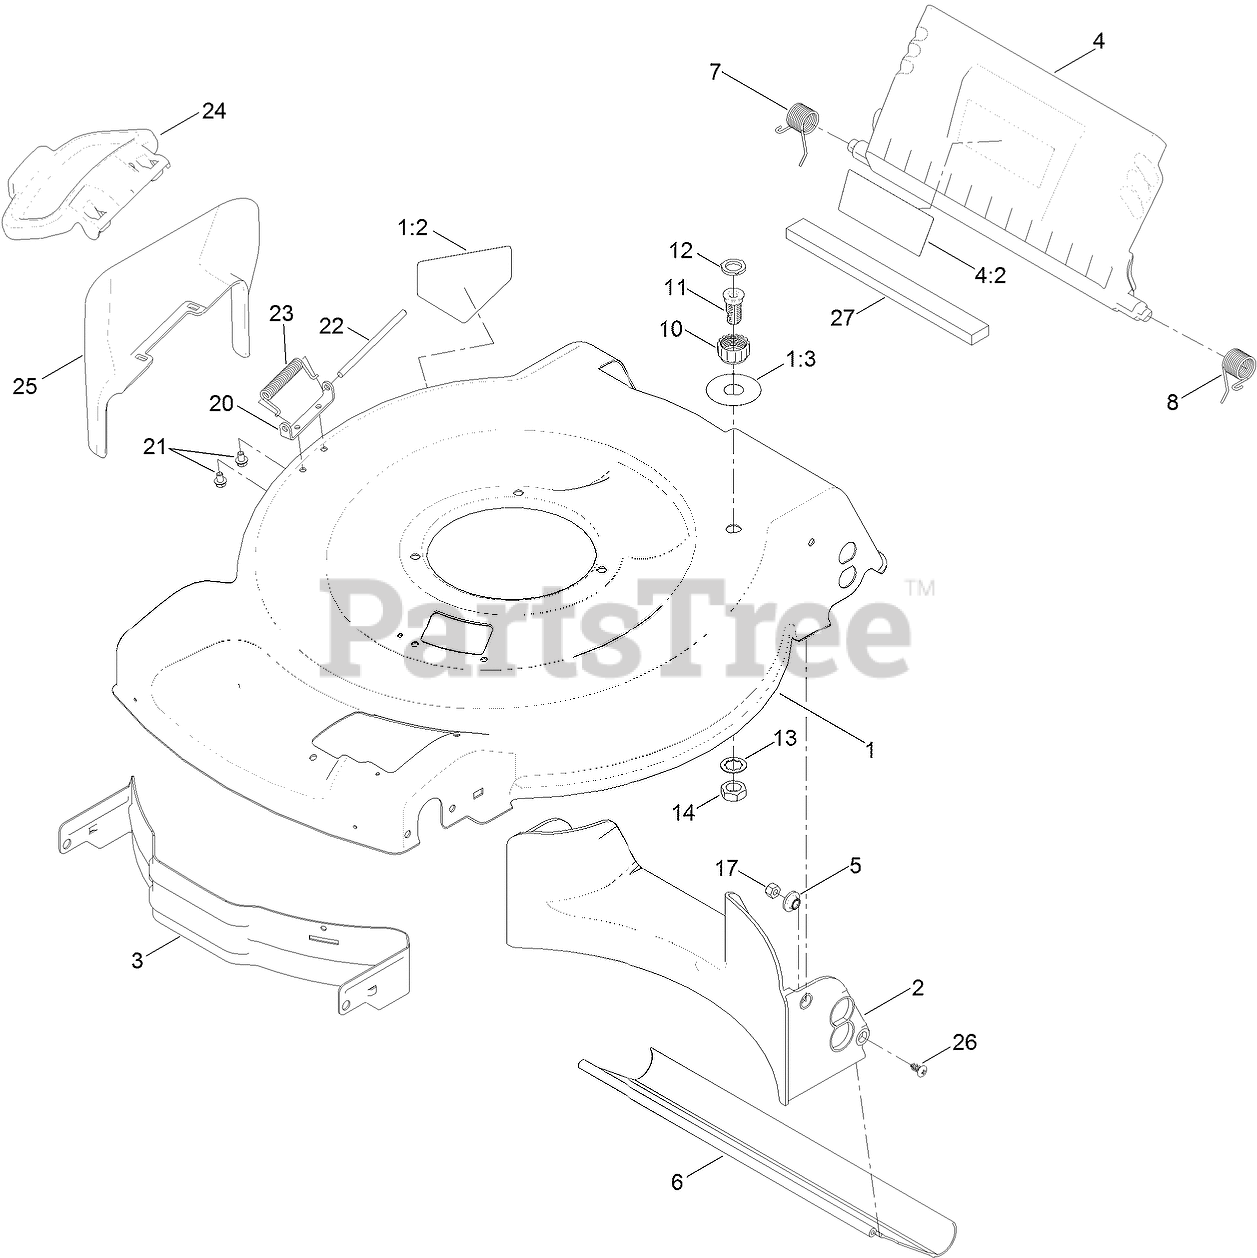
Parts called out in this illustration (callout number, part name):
1	HOUSING ASM
1:2	DECAL-DANGER
1:3	DECAL-PORT, WASHOUT
2	BAFFLE-REAR
3	BAFFLE-FRONT
4	REAR DEFLECTOR ASM
4:2	DECAL-WARNING
5	WASHER-STEPPED, BAFFLE
6	SHIELD-TRAILING
7	SPRING-TORSION
8	SPRING-TORSION
10	COUPLING-HOSE, WASHOUT PORT
11	PORT-WASHOUT
12	WASHER-SEAL, WASHOUT PORT
13	WASHER-LOCK
14	NUT-JAM
17	NUT-LOCK, NI
20	BRACKET-COVER
21	SCREW-HWH
23	SPRING-TORSION
24	DEFLECTOR-SIDE
25	CHUTE-DISCHARGE, SIDE
26	SCREW-PTH
27	FOAM-SEAL
